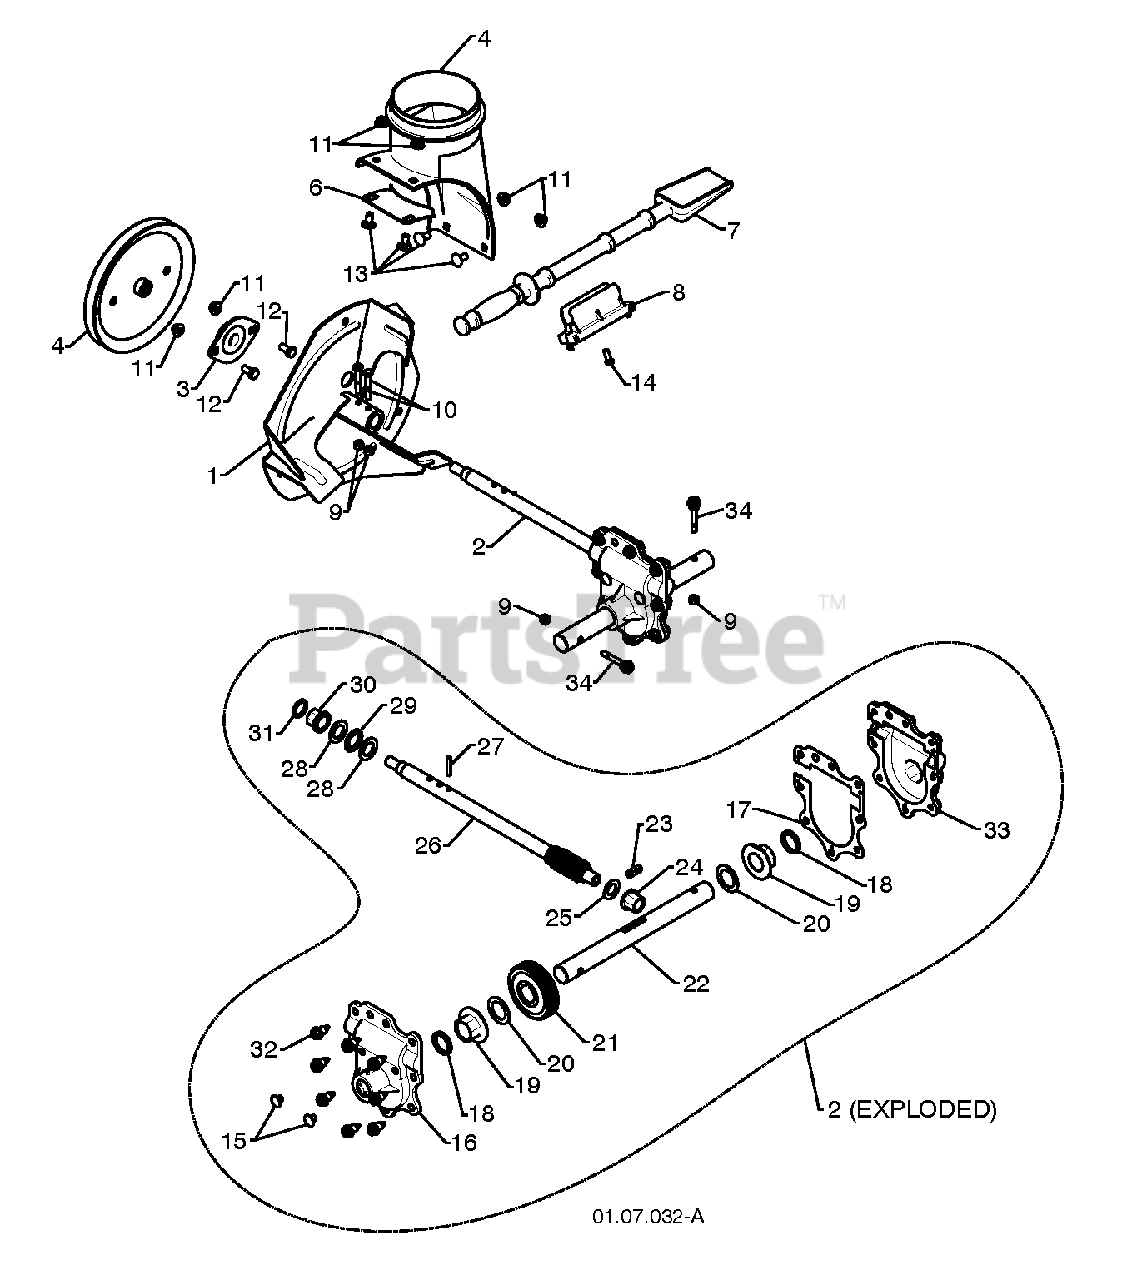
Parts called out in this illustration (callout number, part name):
1	IMPELLER ASSY
2	GEARBOX.AUGER.SCREW.ON.PULLEY
3	BEARING FLANGE
4	PULLEY.IMPELLER.7.5IN.SCREW.ON
5	BASE.DISCHARGE.CHUTE
6	RP BRACKET, CORNER DISCHARGE
7	CLEAN OUT TOOL
8	CLIP.CLEANOUT.TOOL
9	LOCKNUT.NYLOC.1/4-20
10	SCREW.HEX.HD1/4-20X
11	NUTNYLOK.FLRANGE.5/16-18
12	BOLT, HEX HEAD 5/16-18
13	BOLT.CARRIAGE.5/16-18X
14	SCREW.HWH.13-16-5.8.BZP
15	CASE PLUG
16	GEAR.BOX.COVER.RIGHT.SIDE
17	GASKET.GEAR.BOX
18	OIL SEAL
19	FLANGE BUSHING-1"
20	WASHER TRUST 1"
21	WORM GEAR
22	AUGER SHAFT
23	KEY, SQUARE 1/4 X .875
24	FLANGE BUSHING-5/8
25	WASHER, THRUST 5/8
26	SHAFT INOUT 1/2-20
27	PIN, ROLL 3/16 X 1-1/8
28	WASHER, THRUST 3/4
29	BEARING TRUST 3/4 NTA-1220
30	BUSHING, FLANGE 3/4
32	HEX SCREW-5/16 X 3/4
33	GEAR.BOX.COVER.LEFT.SIDE
34	BOLT.SHOULDER.SHEAR.1/4-20.
